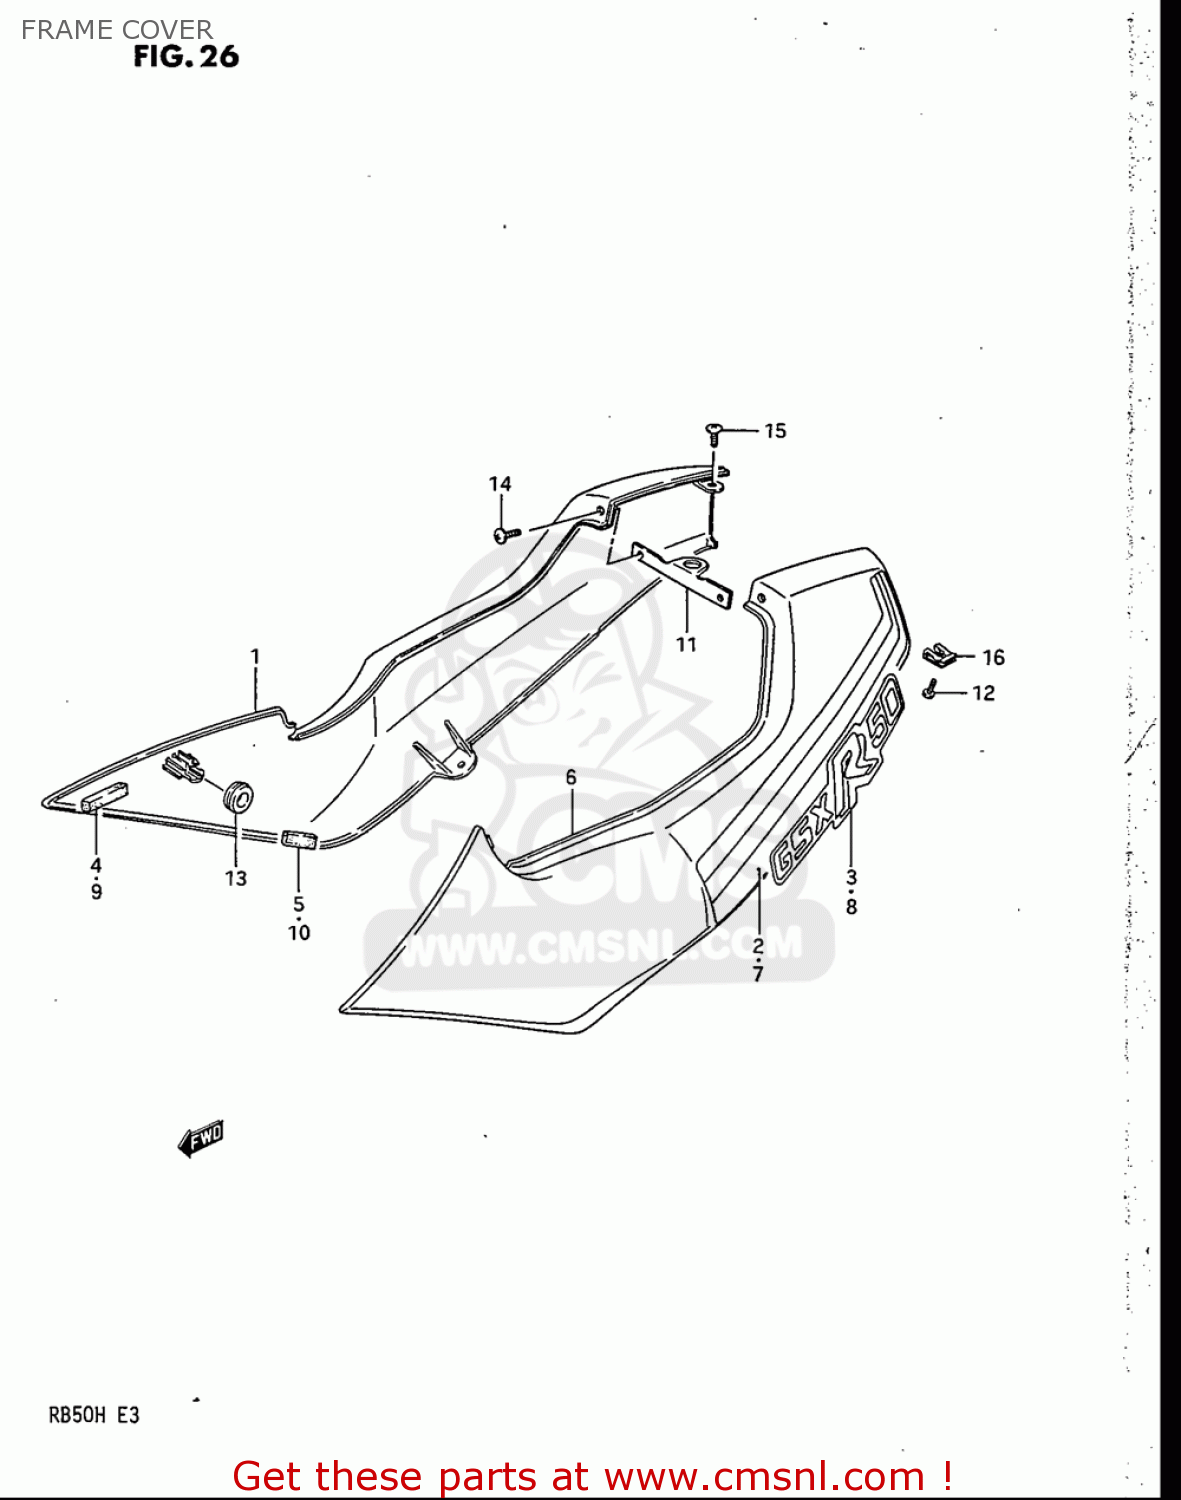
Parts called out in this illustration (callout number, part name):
1	COVER,FRAME,R
6	COVER SET,SIDE,L
7	TAPE SET,SIDE COVER,LEFT
11	BRACKET,SIDE COVER
12	SCREW
13	CUSHION
14	SCREW
15	SCREW
16	NUT
